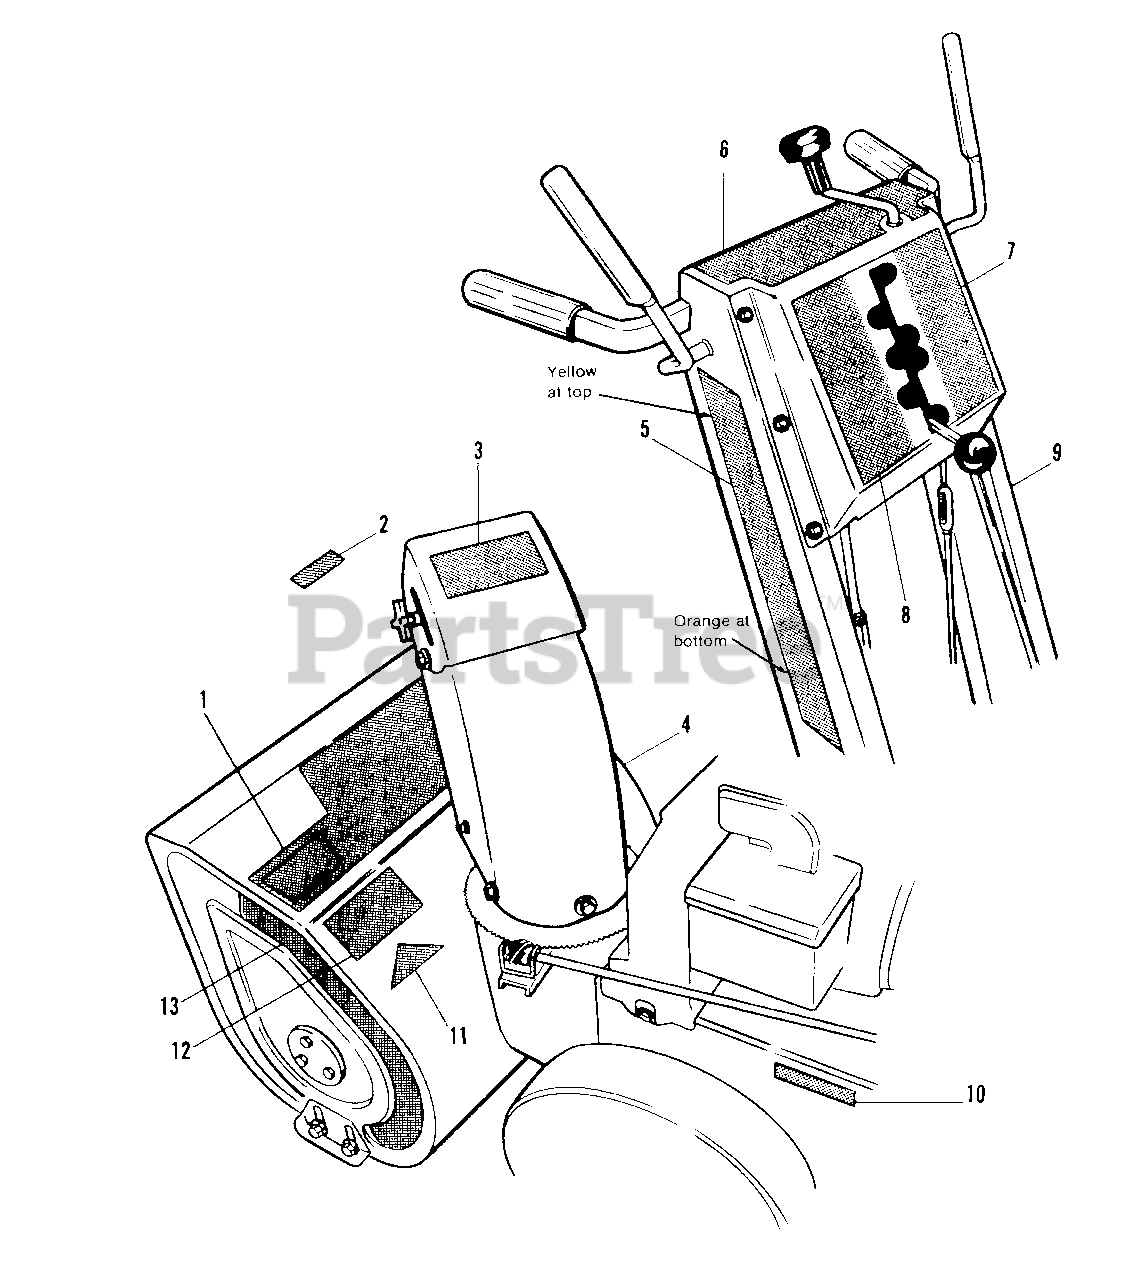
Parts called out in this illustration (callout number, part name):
1	DECAL, Housing, 560
1	DECAL, Housing, 760
1	DECAL, Housing, 860
1	DECAL, Housing, 870
1	DECAL, Housing, 1080
2	DECAL, 12V/120V (1690678, 1690679, 1690778, 1690779, 1691023 & 1691024)
3	DECAL, Warning, Chute
4	DECAL, Hsg., End, R.H.
5	DECAL, Handle, R.H.
6	DECAL, Dash
7	DECAL, Shift Pattern, L.H.
8	DECAL, Shift Pattern, R.H.
9	DECAL, DECAL, Handle, L.H.
10	I.D. Tag
11	DECAL, OPEI
12	DECAL, Warning
13	DECAL, Housing, End L.H.
